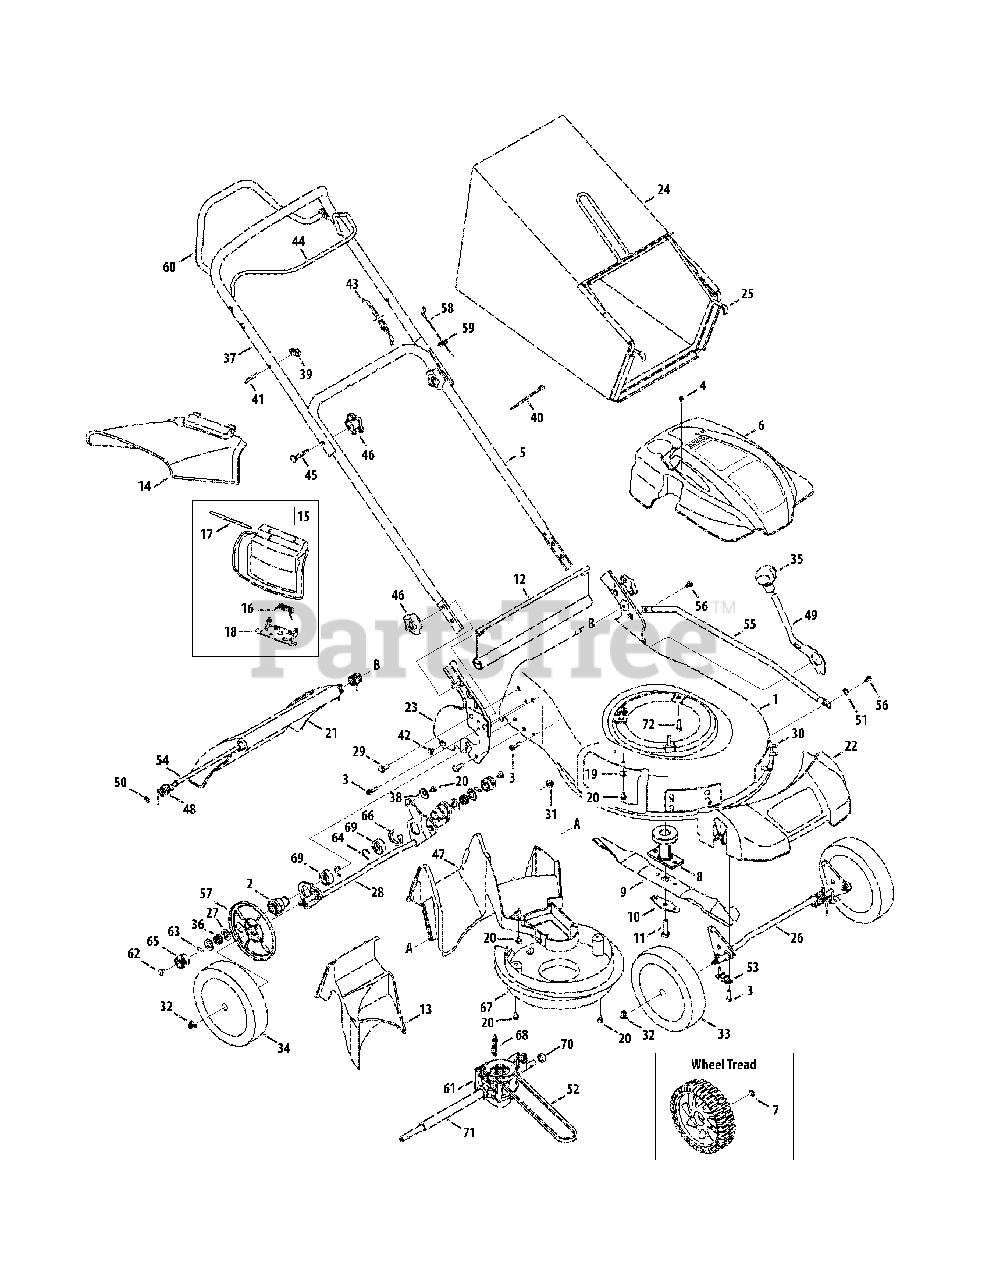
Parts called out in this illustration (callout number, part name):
2	Transmission Support Bearing
3	Screw, 1/4-15 x 1.000
4	Screw, HL, #12-16 x 1.00
5	Lower Handle
6	Engine Shroud
7	Washer, Wave, .510 x .750 x .017
8	Blade Adapter
9	Mulching Blade
10	Blade Bell Support
11	Screw, 3/8-24 x 1.50
12	Trailing Shield
13	Rear Mulch Plug
14	Side Discharge Chute
15	Mulch Plug (Incl. 16-18)
16	Torsion Spring
17	Hinge Pin
18	Chute Deflector Adapter
19	Belleville Washer
22	Front Cover
23	Handle Bracket - RH
23	Handle Bracket - LH
25	Grass Bag Frame
26	Front Bracket Assembly
27	Washer, Flat, .508 x 1.00 x .020
28	Self Propelled Bracket Ass’y
29	Hhcs, 5/16-18 x .625
30	Screw, 5/16-14 x .750
31	Nut, Flange Lock, 5/16-18
32	Nut, Flange Lock, 3/8-16
33	Front Wheel
34	Rear Wheel
36	Wave Spring
37	Upper Handle
38	Washer, Bell, .340 x .872 x .060
40	Cable Tie
41	Rope Guide
42	Screw, #10-16 x .500
43	Control Cable
44	Blade Control
45	Bolt Carriage, 5/16-18 x 2.0
47	Rear Baffle
48	Door Torsion Spring - RH
48	Door Torsion Spring - LH
49	Spring Lever
50	Nut, Push
51	Wshr, Wave, .385 ID x .598 OD
53	Bushing, Lock, .505 Dia. X .62
54	Rear Door Pivot Rod
55	Cross Bracket
56	Scr., Shldr., 1/4-20 x .50
57	Wheel Dust Cover
58	Drive Cable
60	Drive Control
61	Transmission
62	Screw, 1/4-20 x .390
63	Dowel Pin
64	Retainer Ring
65	Spur Gear - RH
65	Spur Gear - LH
66	Spacer, Clip
67	Engine Baffle
68	Exten. Spring, .429OD x 2.515
69	Bearing Support Spacer
70	Sleeve Spacer, .550ID x .340 Lg.
71	Sleeve Spacer, .550ID x 7.97 Lg.
72	Screw, 3/8-16 x 1.00
